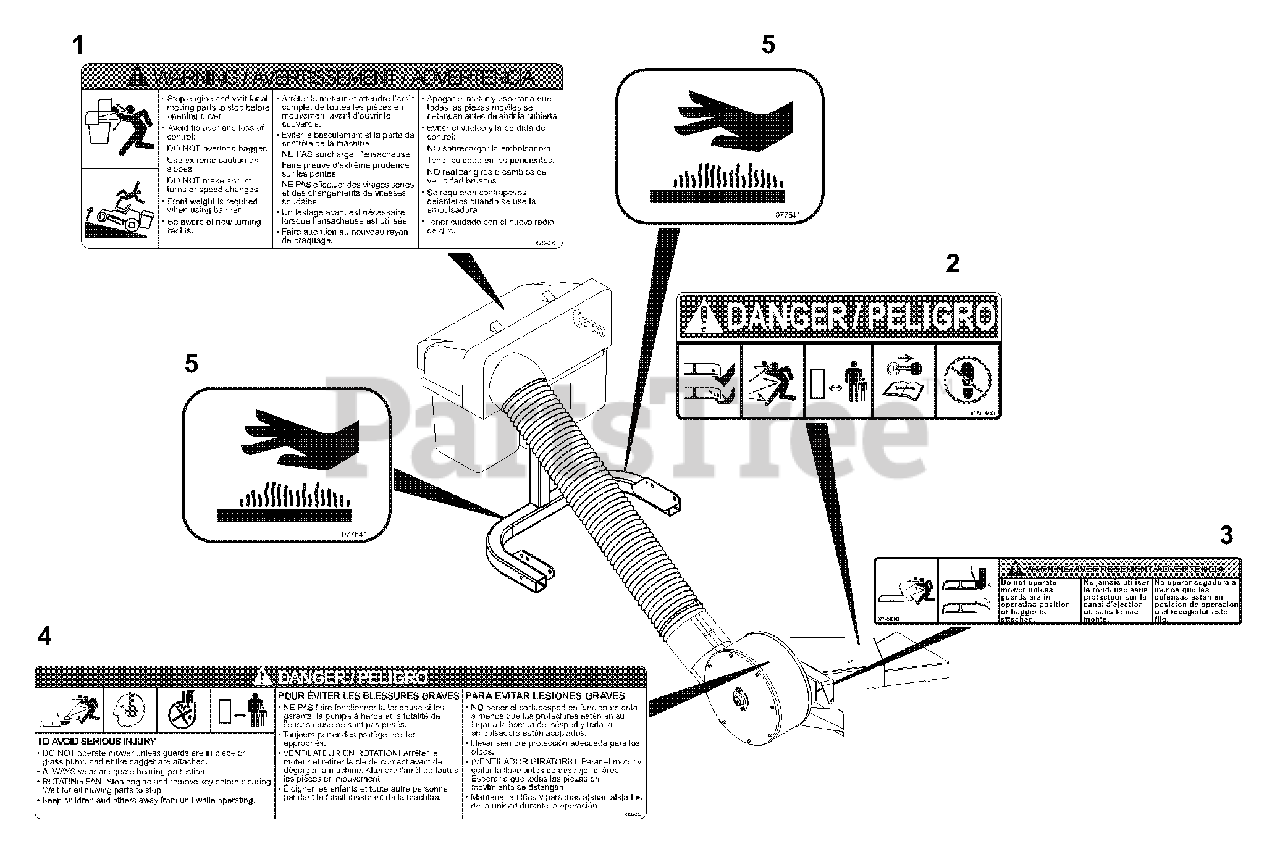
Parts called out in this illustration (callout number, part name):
1	Decal-Warning, Bagger Cover
2	Decal, Mower Pan Head Danger
3	Decal, Warning
4	Decal-Caution, Grass Pump
5	Decal, Hot Surface
